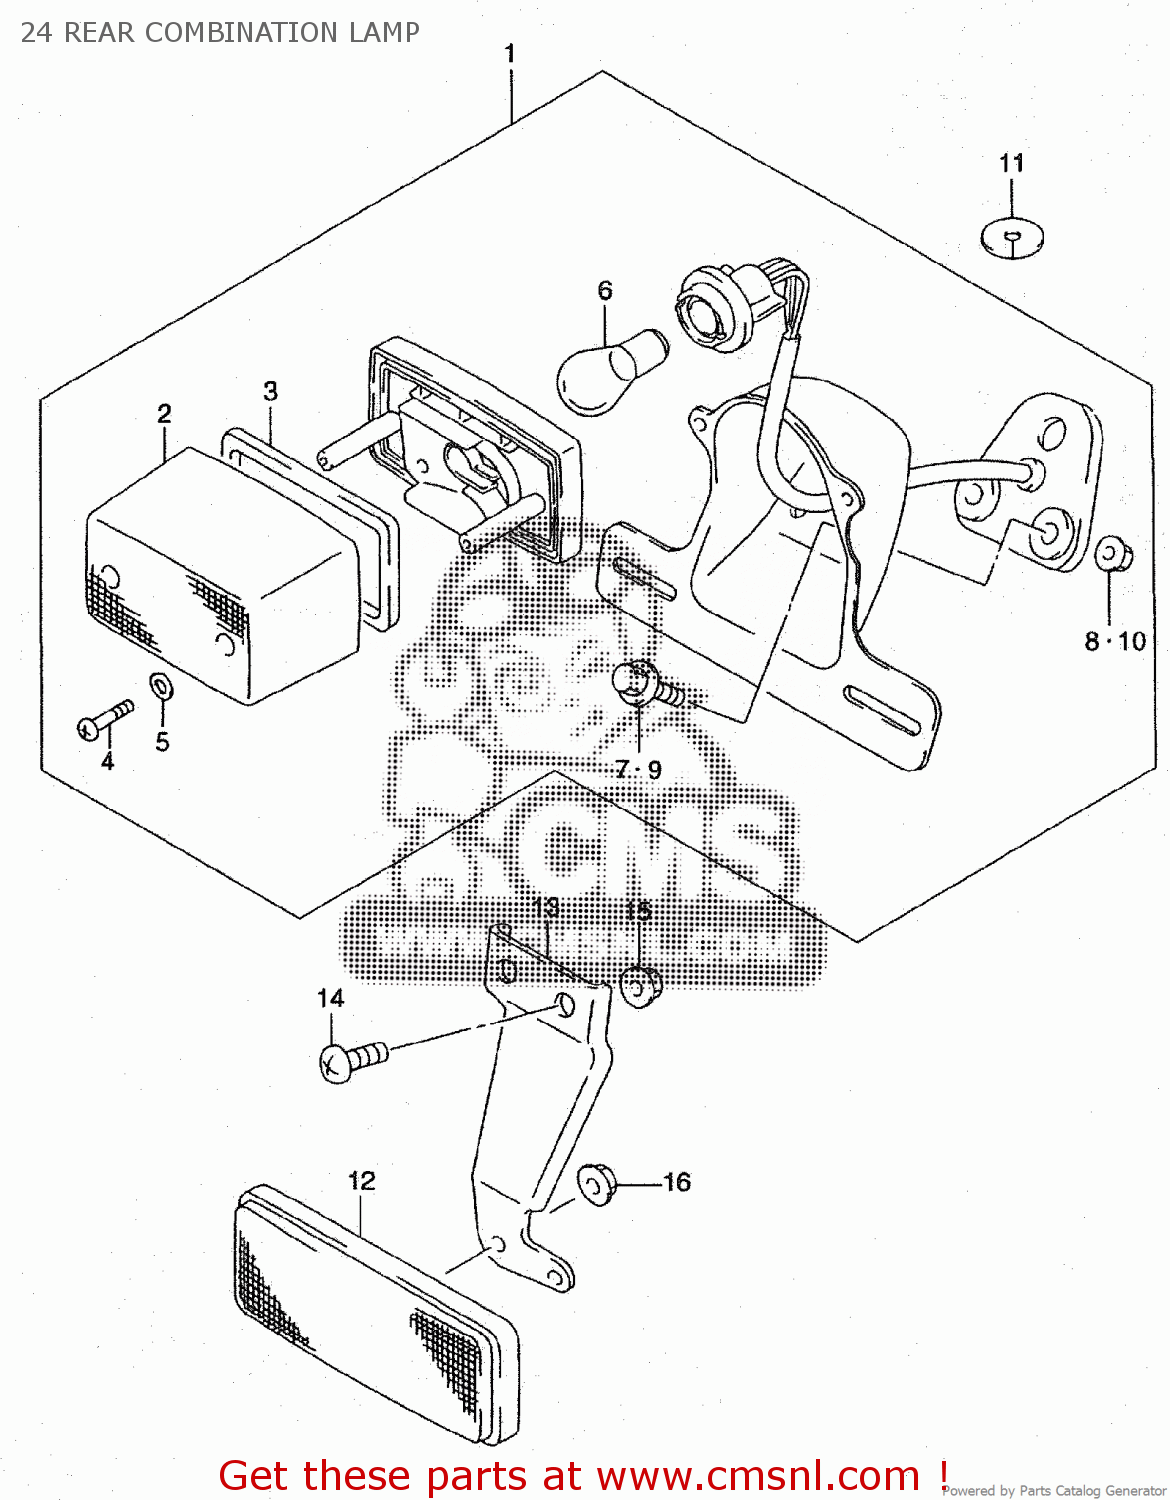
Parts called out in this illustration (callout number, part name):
4	SCREW
5	GASKET (NAS)
6	BULB(12V21/5W,BF141-49642A)
7	BOLT(6X20)
8	NUT
9	BOLT(6X20)
10	NUT
11	GROMMET
12	REFLECTOR ASSEMBLY,REAR
13	BRACKET,RR REFLECTOR
14	SCREW
15	NUT
16	NUT
